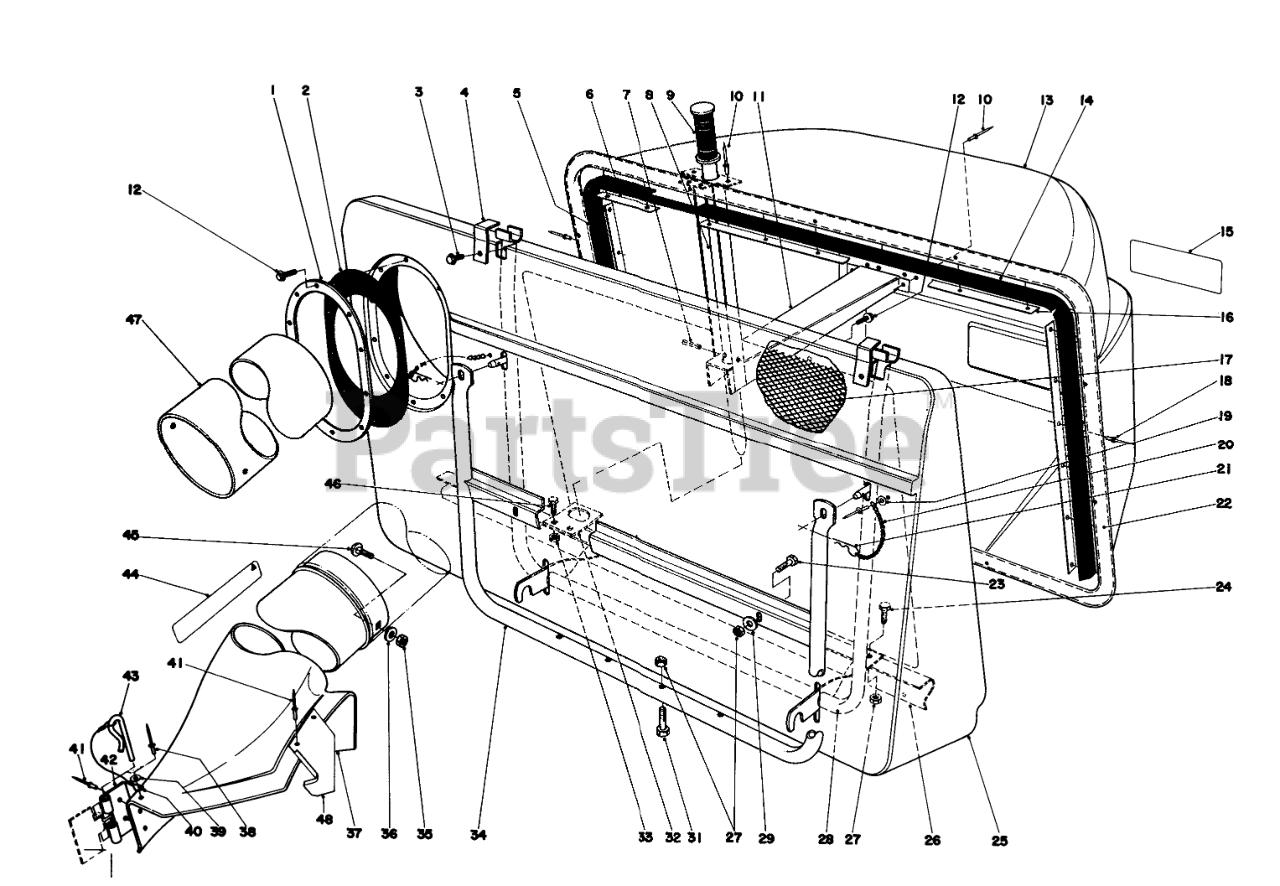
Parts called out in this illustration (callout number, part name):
1	RING-RETAINING
2	RING-RETAINER, RUBBER
3	SCREW-HWH
4	RETNR PIVOT BRKT
5	RH BAG SEAL
6	RETNR TOP EXT.
7	PIN-ROLL
8	DUMP HANDLE ASM
10	Domed Head Rivet
11	Support-Bag Dump Handle
12	SCREW-HWHTF
13	REAR GRASS BASKET
14	Seal-Bag LH.
15	175 Screw
16	BAG RETNR EXT.
17	Screen Bag
19	WASHER
20	10 LINK CHAIN W/O HOOK
21	PIN-HAIR
22	BAG SUPT ASM FRM
23	SCREW-HH
24	SCREW-HH
25	Bag Front
26	FRAME SUPT BRKT B
27	NUT-LOCK, CONE
28	Bag Frame
29	WASHER-PLAIN
31	SCREW-HH
32	Hanger-Frame Lower
33	NUT-LOCK, CONE
34	BAG SUPPORT WA
35	NUT-KEPS
36	WASHER-FLAT
37	Chute Assembly (Incl. Ref. #38-44 & 48)
38	RIVET-BLIND
39	WASHER-PLAIN
40	LANYARD
41	RIVET-BLIND
42	BRACKET-MOUNTING, CHUTE
43	PIN-LOCKING, CHUTE
44	Decal-Chute
45	Bolt-Carriage
46	SCREW-HH
47	Duct
48	CHUTE SUPT BRKT
